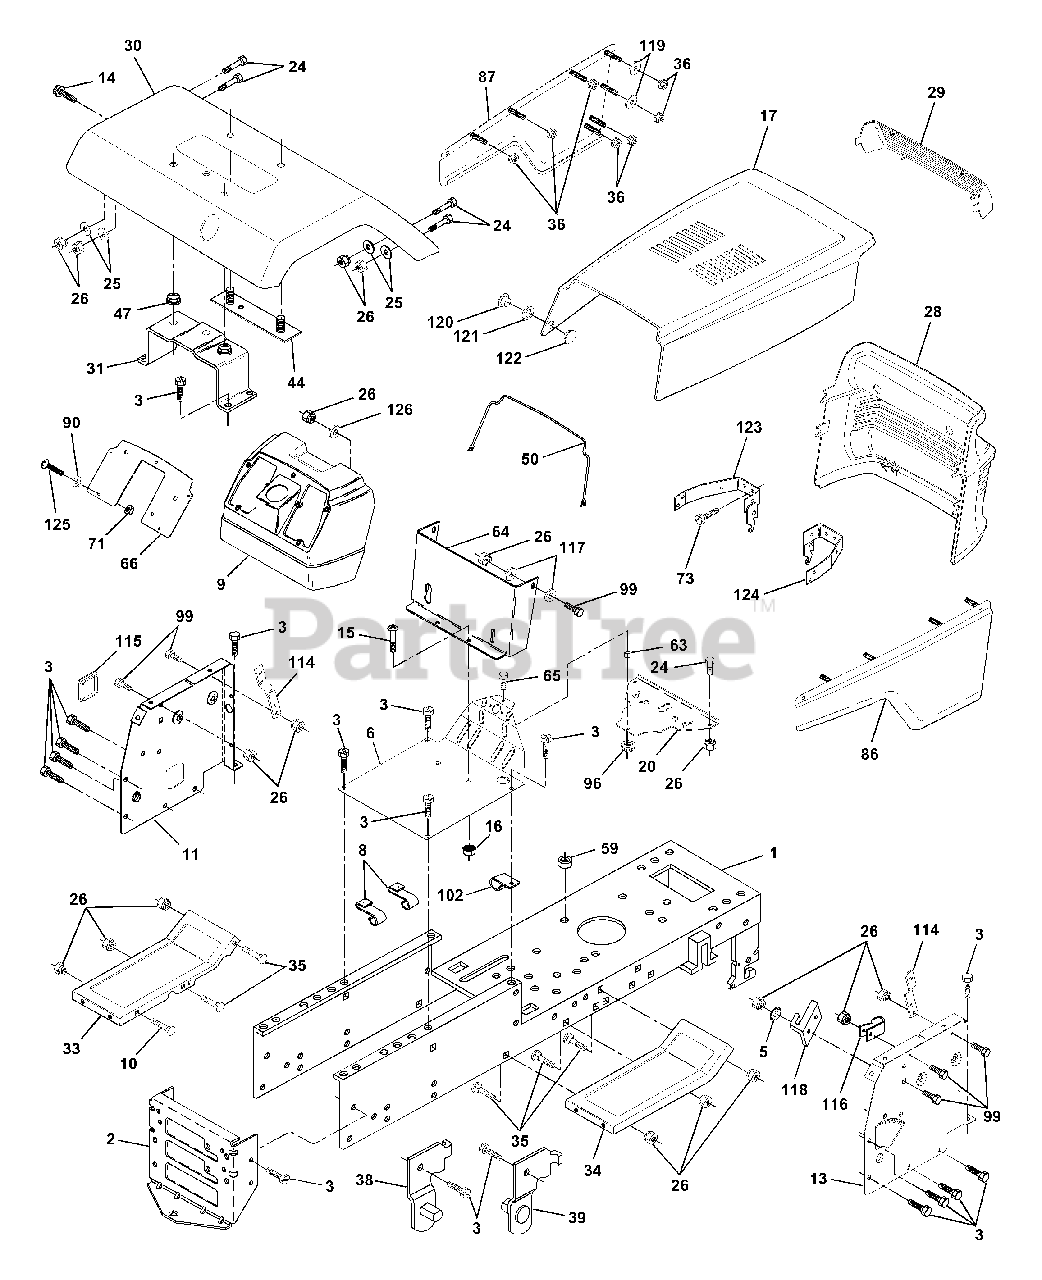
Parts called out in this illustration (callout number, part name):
1	Chassis Weldment 12 ga 38/42
2	Drawbar Stretch
3	Screw Thdrol 3/8 - 16 x 3/4 Ty-TT
6	Saddle Slkscr
8	Clip Insulator
9	Dash Black Hole "a" 88
10	Bolt Carriage
11	Panel Pnt Dash Lh
13	Panel Pnt Dash Rh
14	Screw Thdrol 3/8 - 16 x Ty-TT
15	Screw Mach Trhd 5/16 - 18 UNC x 3/4
16	Nut Keps 5/16 - 18 UNC
20	Plate Pnt Sprt Battery (blk)
24	Bolt Hex 3/8 - 16 x 3/4
25	Washer 13/32 x 13/16 x 12 Ga
26	Nut Lock 3/8
28	Grille YT GT Husqvarna
29	Lens Headlight Rh Smoked
30	Fender Pnt
31	Bracket Pnt Fender
33	Footrest Pnt Lh
34	Footrest Pnt Th
35	Bolt Rdhd Sht Sqnk 3/8 - 16 x 3/4
38	Bracket Asm Pivot Lh
39	Bracket Asm Pivot Rh
42	Lens Headlight Lh Smoked
44	Strap Asm. Fender
47	Nut Push Nylon
50	Support Pnt Dash
51	Nut Lock w/Insert 1/4-20 UNC
59	Bushing Snap Split
63	Spacer Split 59/ x 1.25 Blk/zin
64	Dash Pnt Lower
65	Bolt Fin Hex 5/16 - 18 Unc x 2 Gr. 2
66	Plate Silkscreened Dash
67	Washer 11/32 x 11/16 x 16 Ga
68	Nut Keps Hex 1/4 - 20 UNC
69	Strap Asm Pnt Hinge Rear (blk)
70	Strap Asm Pnt Hinge Front
71	Nut Keps Blk Hex 1/4-20 UNC
72	Support Asm Grille
74	Nut Crownlock 3/8-16 UNC
75	Bolt, Shoulder 1/4 - 20 UNC
76	Botl Fin Hex 3/8 - 16 Unc x 1-1/4
77	Screw Mach Cr Pan #10-24 x 1/2
78	Washer Lock #10
79	Nut Weld .327/.304 #10 - 24
80	Latch Chute Blk
81	Nut Plastic Locking Wng 1/4 - 20
82	Screw Mach Cr Pan #10 - 24 x 1-1/4
83	Spacer Split #10 x 3/4 Cad/Zin
84	Washer 7/32 x 1/2 x 18 Ga
85	Nut Keps #10 - 24 Unc
86	Panel Pnt Rh Side
87	Panel Pnt Lh Side
90	Washer 9/32 x 3/4 x 16 Ga
91	Nut Fin Hex 1/4 - 20 Unc
92	Washer Lock Hvy Helical 1/4
93	Grille Asm
94	Cap Washer Snap Nat.
95	Cap Snap Black
96	Nut Lock Hex w/ins 5/16 - 18 Unc P
97	Bracket Asm Fr Pvt Hinge Lh
98	Bracket Asm Fr. Pvt Hinge Rh
99	Bolt Fin Hex 3/8-16 x 1
109	Bracket Extension Bumper
110	Plug Plastic
111	Bolt Carriage 3/8-16 x 1-1/4
112	Washer 13/32 x 13/16 x 16 Ga.
113	Bumper Asm.
